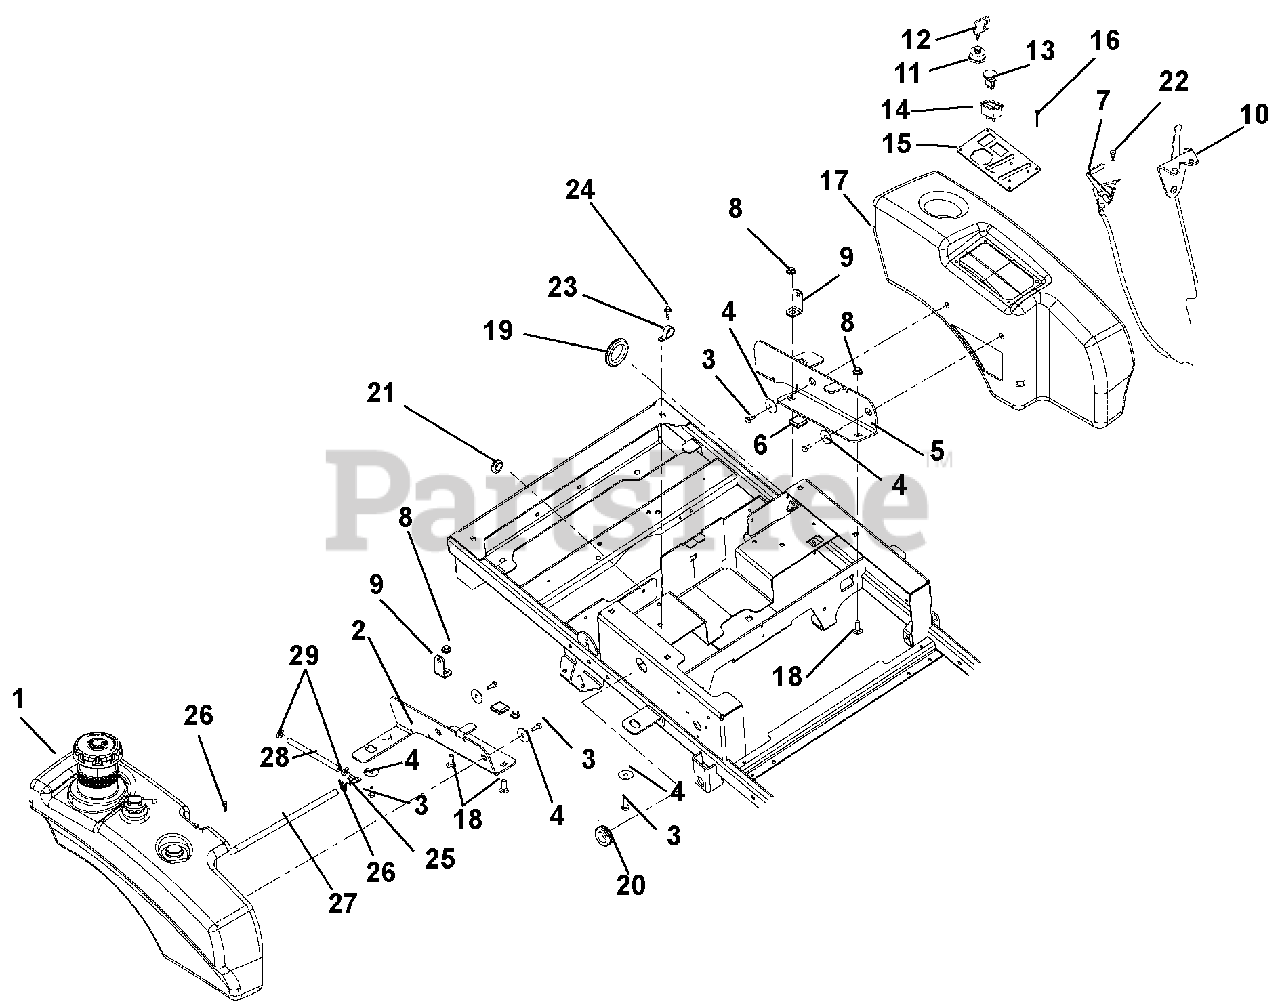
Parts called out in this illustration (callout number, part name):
1	TANK, XL NON-PERM ASSEMBLY
2	BRKT, RH REAR TANK MOUNT
3	BLT-SERHFWH .312-18X.50 YWZC
4	WSHR-FL-STL .347X1.254X.048YWZ
5	BRKT, LH REAR TANK MOUNT
6	GRIP, RUBBER (1.0X1.0X.187)BLK
7	CABLE, XL THROTTLE
8	@NUT-LK-NYL-FLG .38-16 YWZC
9	BRKT, HOOD PIVOT
10	CABLE, XL CHOKE
11	KEY SWITCH
12	KEY -W/CAP
13	SWITCH, CLUTCH
14	METER, HOUR W/MAINTENANCE
15	CONTROL PANEL
16	SCR-HEX .25X14-.75
17	FENDER, XL
18	@BLT-RDHDSQNK .38-16X1.00 G5YZ
19	GROMMET 1.70ID X 2.0OD
20	GROMMET 1.0ID X 1.38 OD
21	GROMMET,RUBBER 5/8 ID/1.13 OD
22	@SCR-TAP 10-24X.50 HWH TR YWZC
23	CLAMP, CUSHIONED STEEL .75
24	@SCR-TAP .38-16X.50 HWH TR YWZ
25	FITTING-3/16X1/4 90DEGREE VAC
26	CLAMP, FUEL LINE
27	HOSE, .25 LOW-PERM BULK GAS
28	HOSE, .188 LOW-PERM BULK GAS
29	CLAMP-HOSE, SPRING .188
30	CAP, END .315 X 1.00
